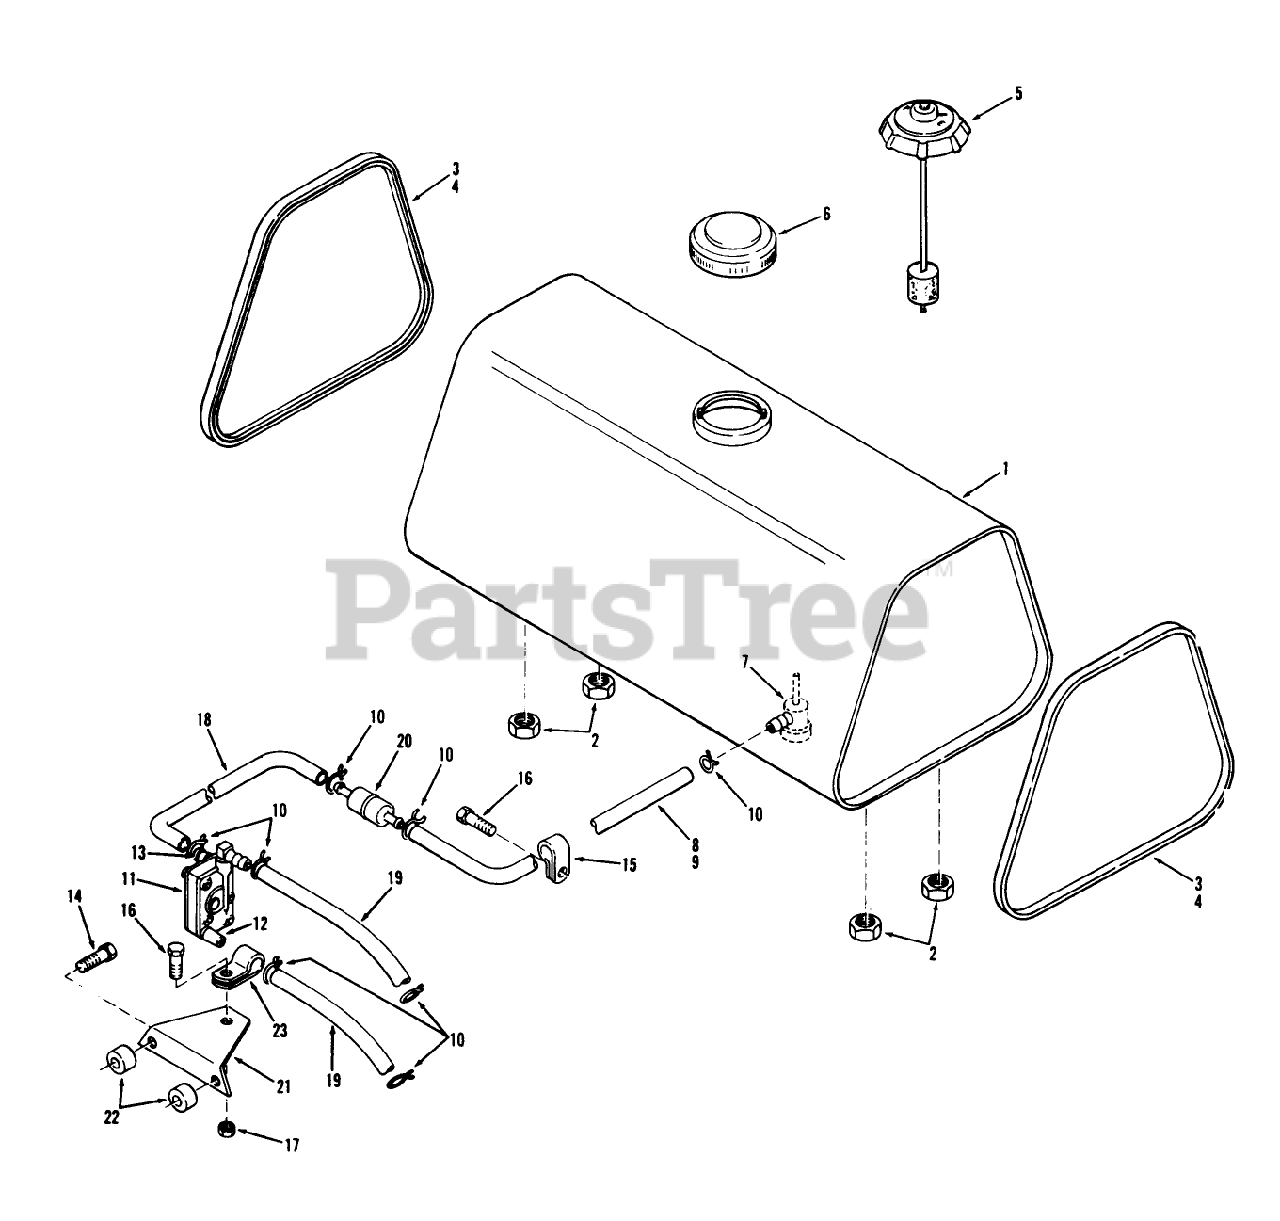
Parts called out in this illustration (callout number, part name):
4	GAUGE CAP
5	GAUGE CAP
22	BEARING CAM ROLLER
